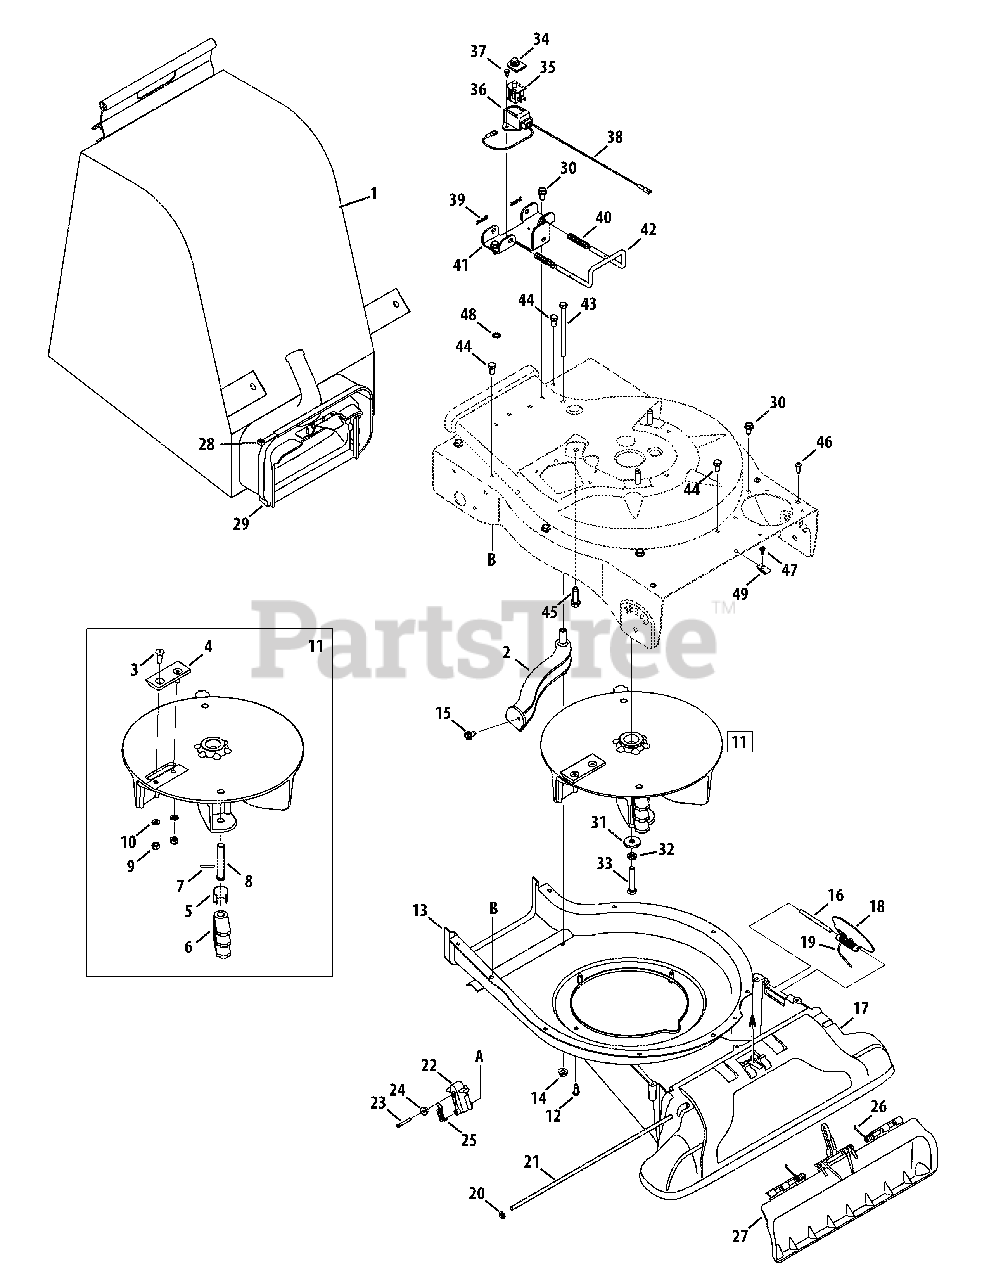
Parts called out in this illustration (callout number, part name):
1	Bag Assembly (incl. Ref 28)
2	Screen Assembly
3	Hex Screw 5/16-24 x 1.0
4	Chipper Blade
7	Spiral Pin
8	Clevis Pin
9	Lock Nut, 5/16-24
10	Lock Washer, 5/16
11	Impeller Assembly
12	Shoulder Screw, #12-24 x.30 x.46
13	Lower Flail Housing
14	Flange Lock Nut 5/16-18
15	Screw, 5/16-18 x.500
18	Base Adapter Door
19	Torsion Spring
20	Cap Speed Nut 1/4
21	Pivot Rod
22	Nozzle Door Lever
23	Hex Screw, #8-18 x 1.25
24	Shoulder Spacer
25	Extension Spring
26	Nozzle Door Torsion Spring
27	Nozzle Door
28	Tie Strap, 42"
29	Chute Assembly
30	Hex Index Screw, 5/16-12 x.750
31	Flat Washer.375 ID x 1.25 OD
32	Lock Washer 3/8
33	Hex Cap Screw 3/8-24 x 2.0
34	Switch Cover
35	Safety Switch
36	Safety Switch Cover
37	Hex Washer Screw #10-16 x.50
38	Wire Harness
39	Cotter Pin
40	Compression Spring
41	Mounting Bracket
43	Hex Cap Screw 5/16-18 x 4.5
44	Hex Cap Screw 5/16-18 x.625
45	Hex Washer Screw 3/8-16 x 1.00
46	Screw, #12-16 x.750
47	Screw #10 - 16 x.500
48	External L-Washer 5/16
49	Speed Nut
